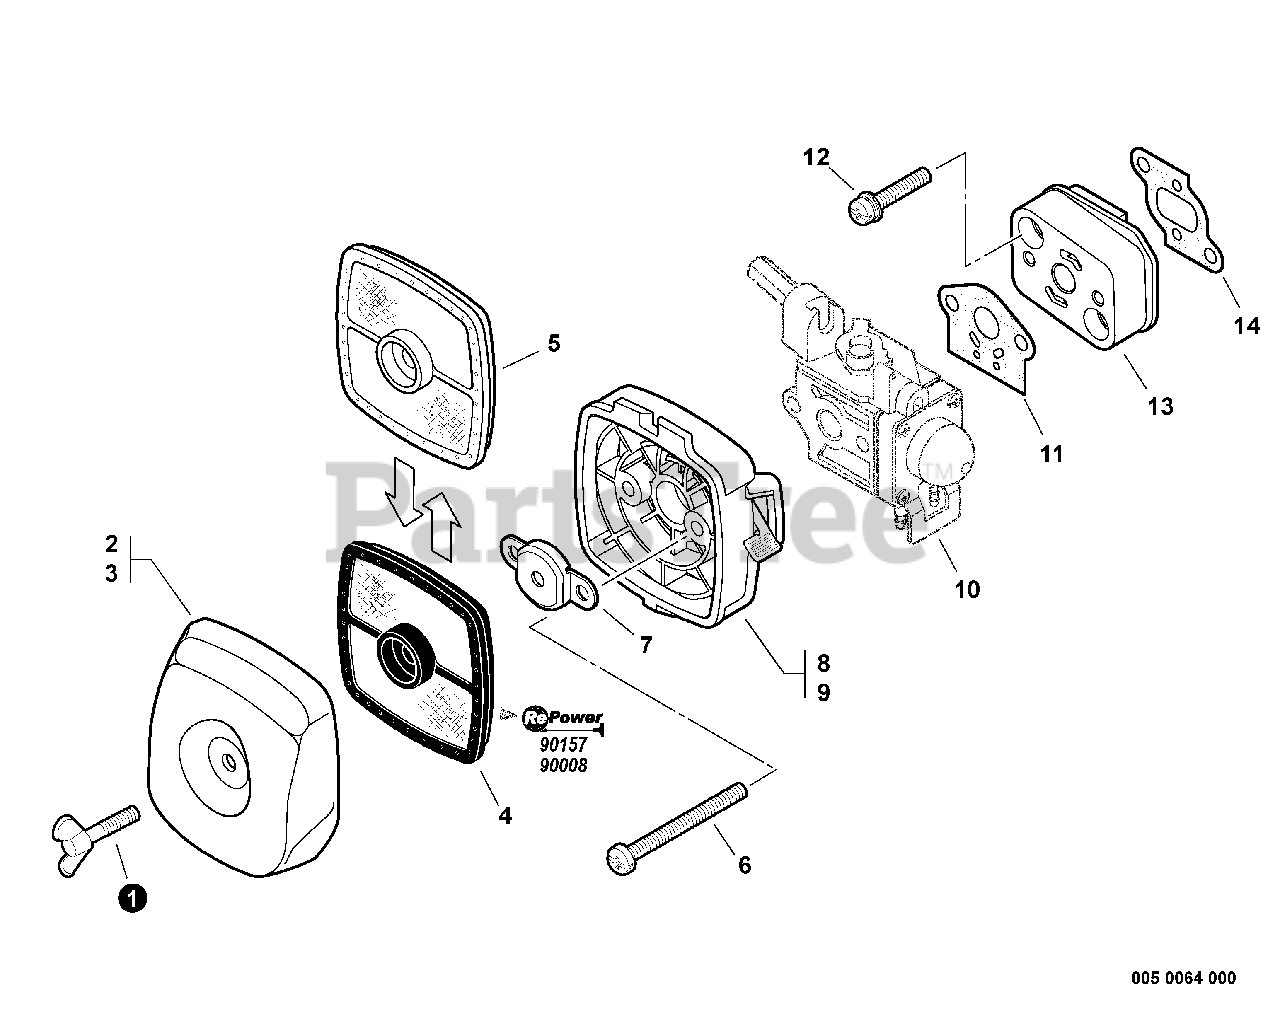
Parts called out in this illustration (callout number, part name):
1	BOLT, WING 5×20
2	COVER, AIR FILTER - GRAY
3	COVER, AIR FILTER - BLACK
4	FILTER, AIR - DOUBLE LAYER
5	FILTER, AIR - SINGLE LAYER
6	SCREW 5×60
7	PLATE, PREVENT
8	CASE, AIR FILTER - GRAY
9	CASE, AIR FILTER - BLACK
10	CARBURETOR
11	GASKET, CARBURETOR
12	BOLT 5×25
13	INSULATOR, INTAKE
14	GASKET, INTAKE
15	TUNE-UP KIT
16	FILTER KIT - REPOWER
